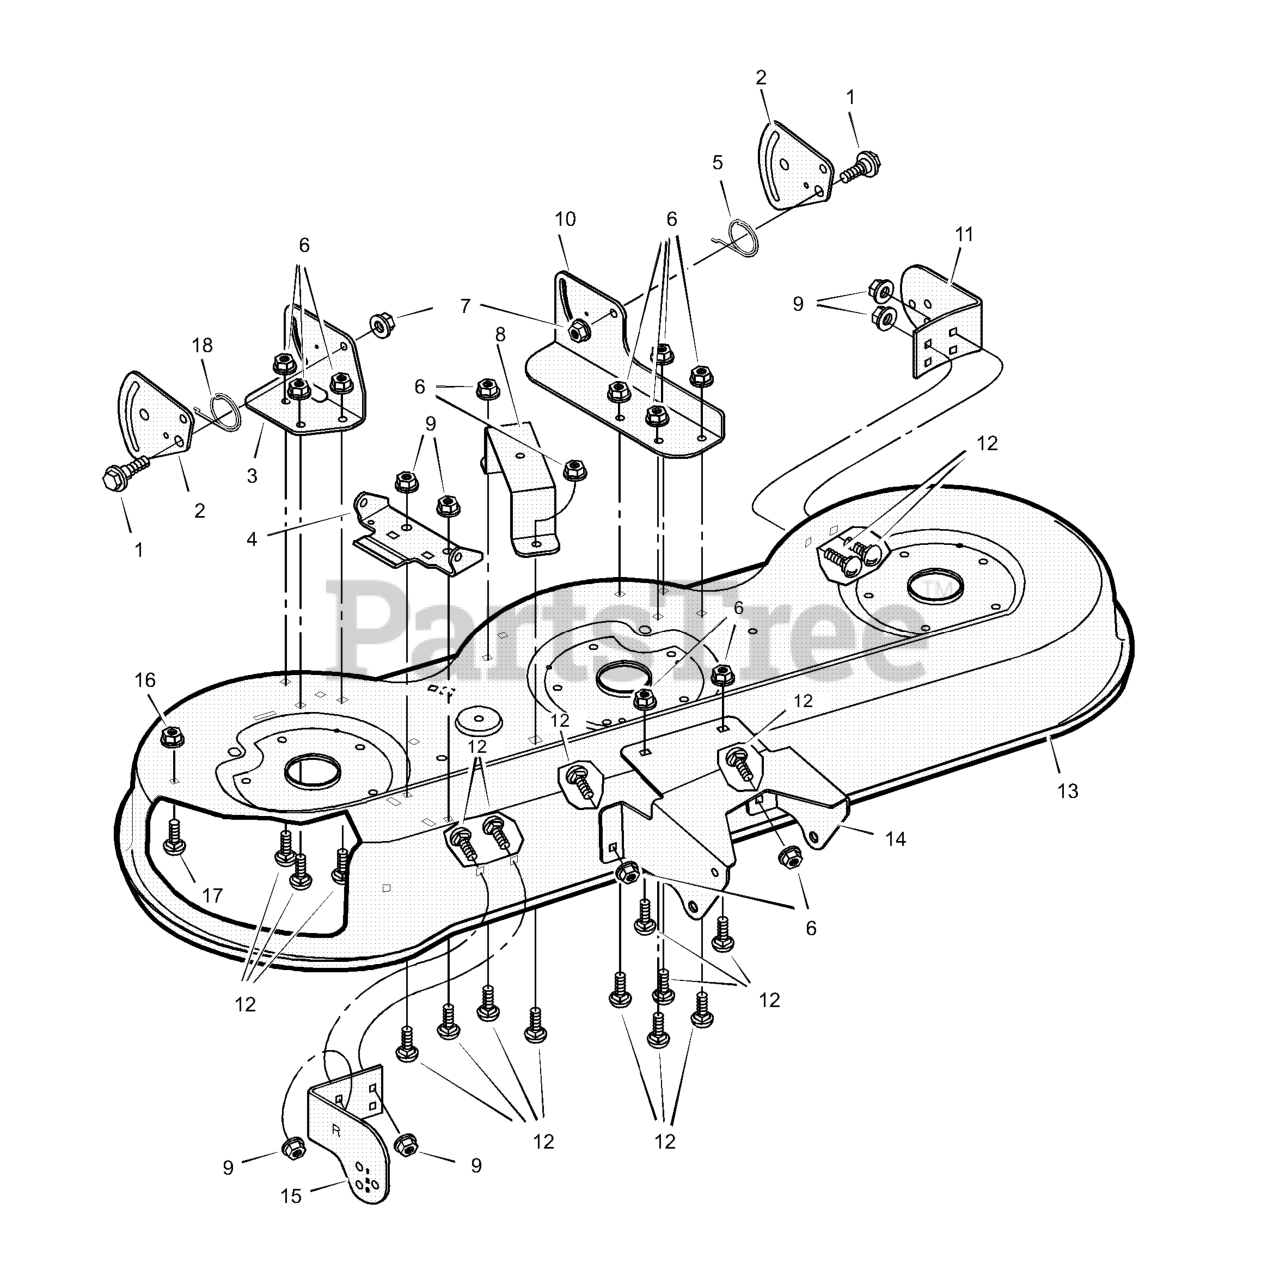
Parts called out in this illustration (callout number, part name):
1	Bolt, Shoulder
2	Plate, Suspension
3	Bracket, Right Rear
4	Bracket, Hinge
5	Spring, Left
6	Nut, Flange
7	Nut, Flange
8	Bracket, Bell Crank
9	Nut, Flange
10	Bracket, Left Lifter
11	Bracket, Left Gauge Wheel
12	Bolt, Carriage
13	Housing, Blade
14	Bracket, Front Deck
15	Bracket, Right Gauge Wheel
16	Retainer
17	Bolt, Carriage
18	Spring, Right
